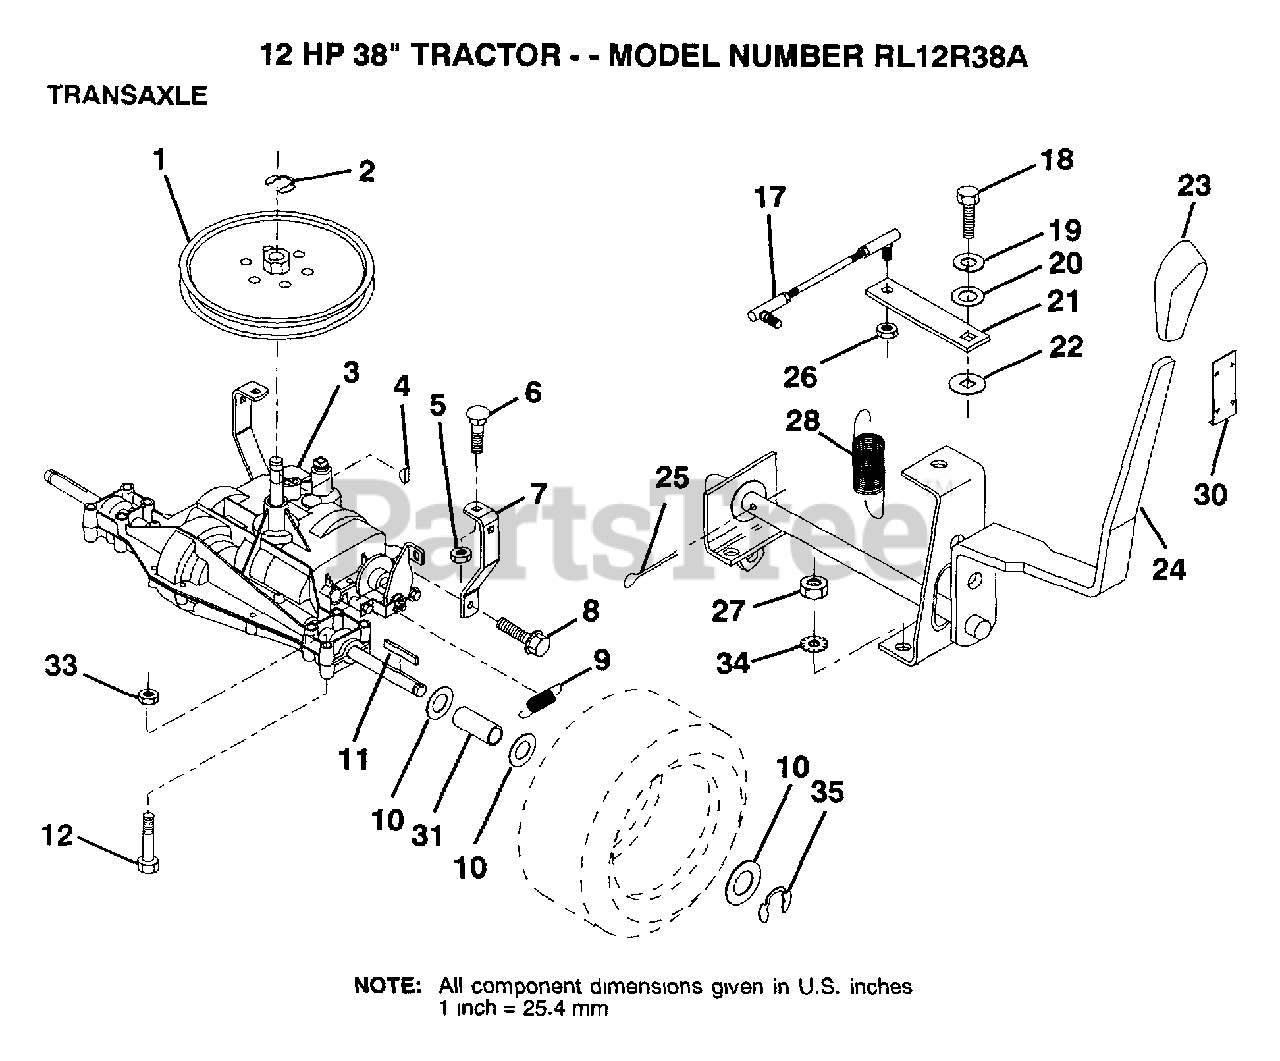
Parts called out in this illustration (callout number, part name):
1	PULLEY
6	BOLT
7	"STRAP,TORQUE"
8	SCREW
10	WASHER
11	SQUARE KEY
12	BOLT
17	"LINK,SHIFT"
19	LOCKWASHER
20	WASHER LT
21	"ARM,SHIFT"
22	WASH-SHFT PLT LT
23	"KNOB,SHT CONTROL"
25	PIN COTTER 1/8
26	NUT.LOCK.5/16-24
28	"SPRING,EXT"
30	KNOB RETAINER
31	SPACER
34	LOCKWASHER.5/16.E
35	E-RING LT
